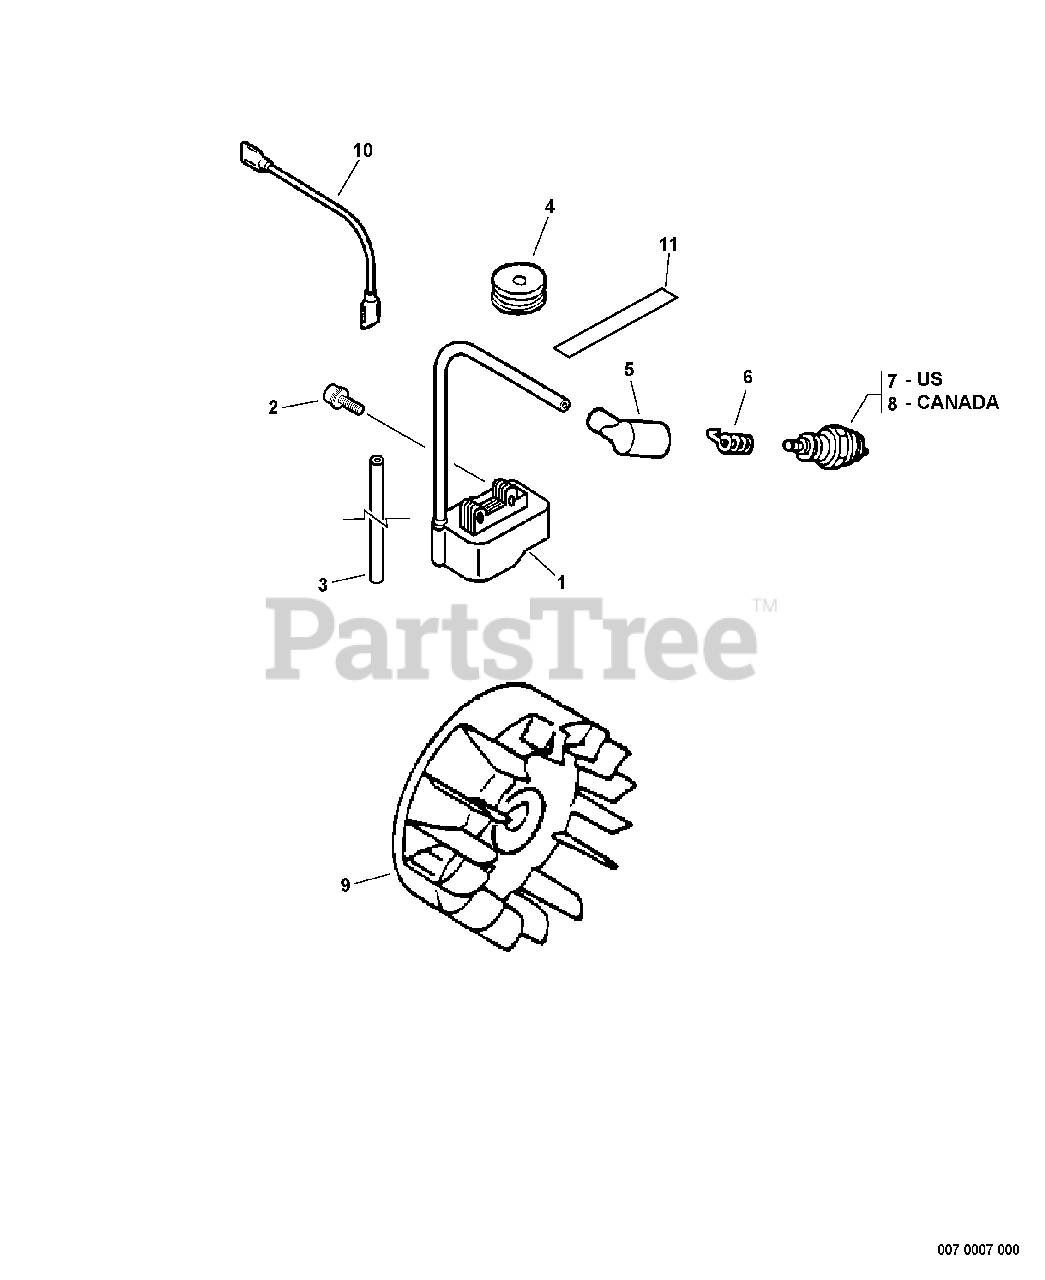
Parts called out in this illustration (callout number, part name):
1	COIL, IGNITION
2	SCREW - 4X20
3	TUBE, INSULATOR
4	GROMMET
5	CAP, SPARK PLUG
6	TERMINAL, SPARK PLUG CAP
7	SPARK PLUG -- BPM-8Y
8	SPARK PLUG -- BPMR-8Y
9	FLYWHEEL
10	LEAD - GROUND
11	LABEL - SPARK PLUG -- BPM-8Y
